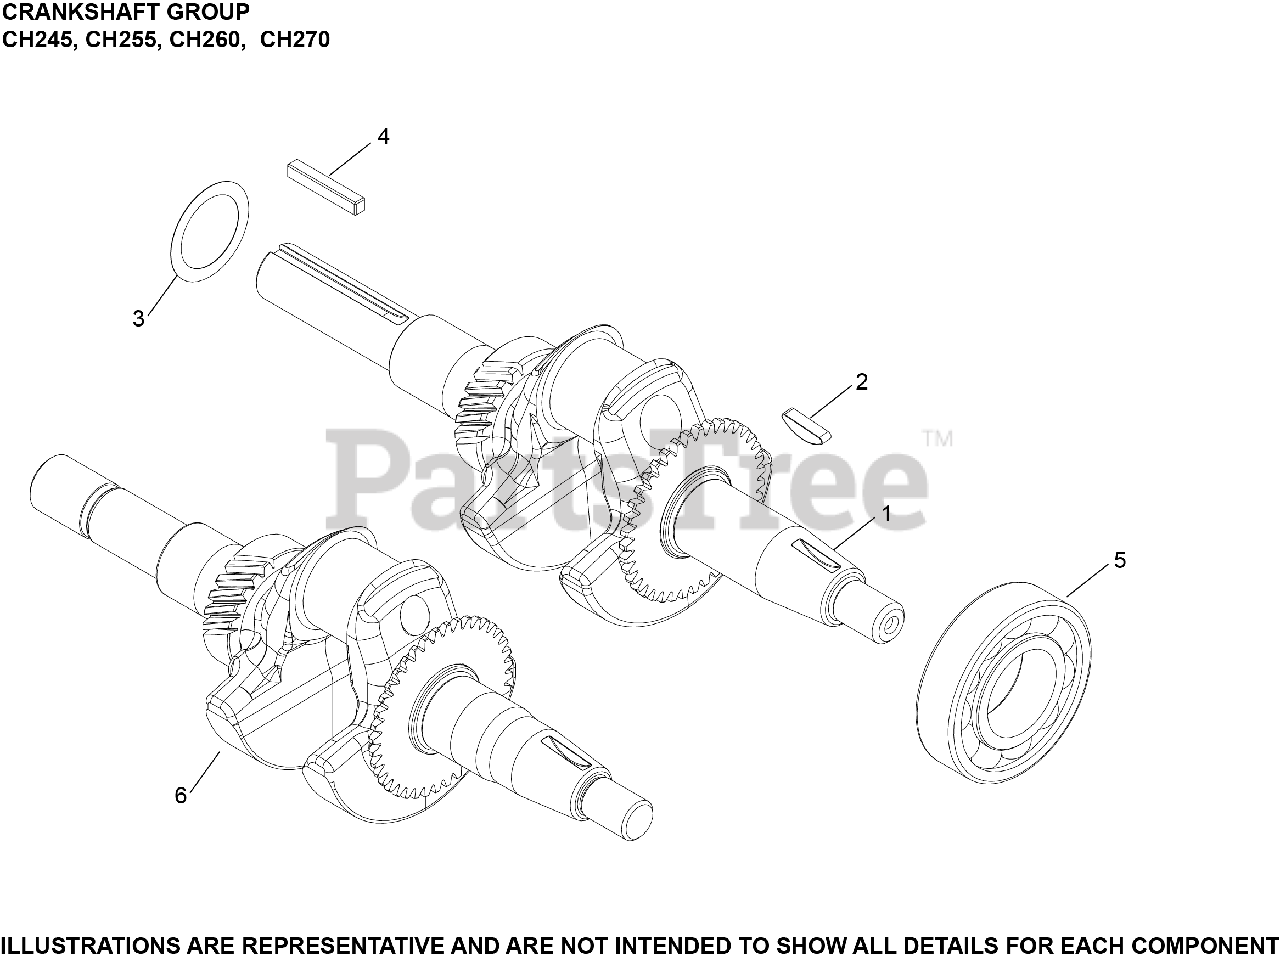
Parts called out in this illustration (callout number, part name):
1	CRANKSHAFT, ASSEMBLY
2	KEY, FLYWHEEL
3	KIT, THRUST SHIM
4	KEY, SQUARE
